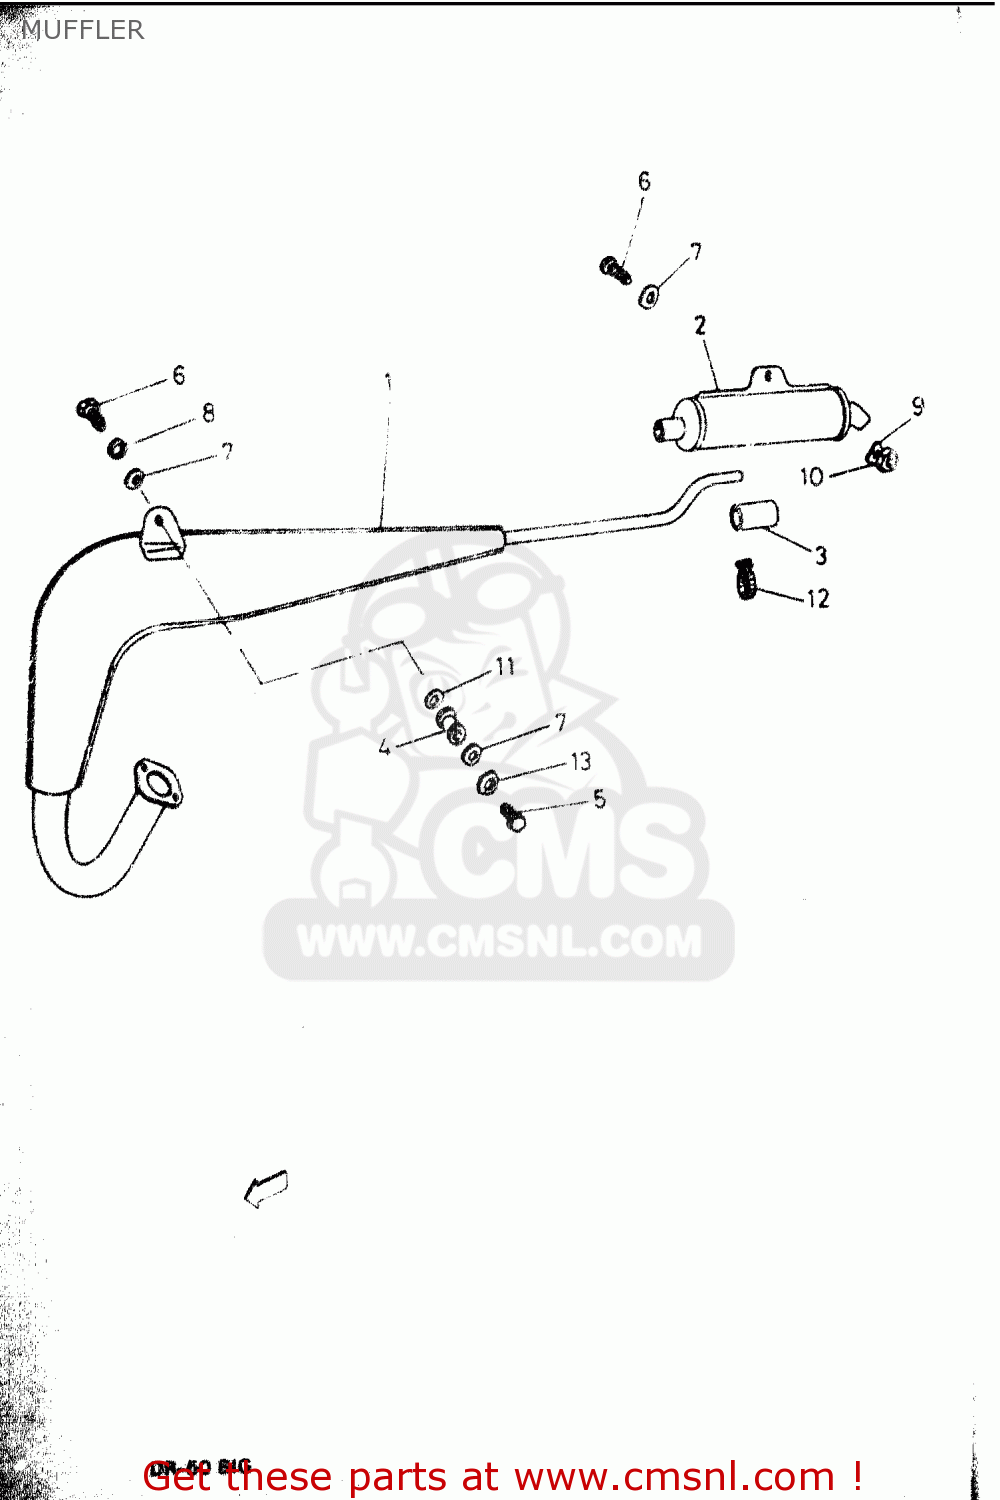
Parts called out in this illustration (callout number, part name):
1	MUFFLER, 1ST
2	MUFFLER, 2ND
3	CONNECTOR
4	BUSH
5	SCREW M8X10 DIN 933
6	SCREW M8X15 DIN 933
7	WASHER B8 DIN 125
8	WASHER A8 DIN 127
9	WASHER B8 DIN 137/N
10	NUT M8 DIN 934
11	KLINGERIT
12	CLAMP
13	WASHER A8 DIN 6798
